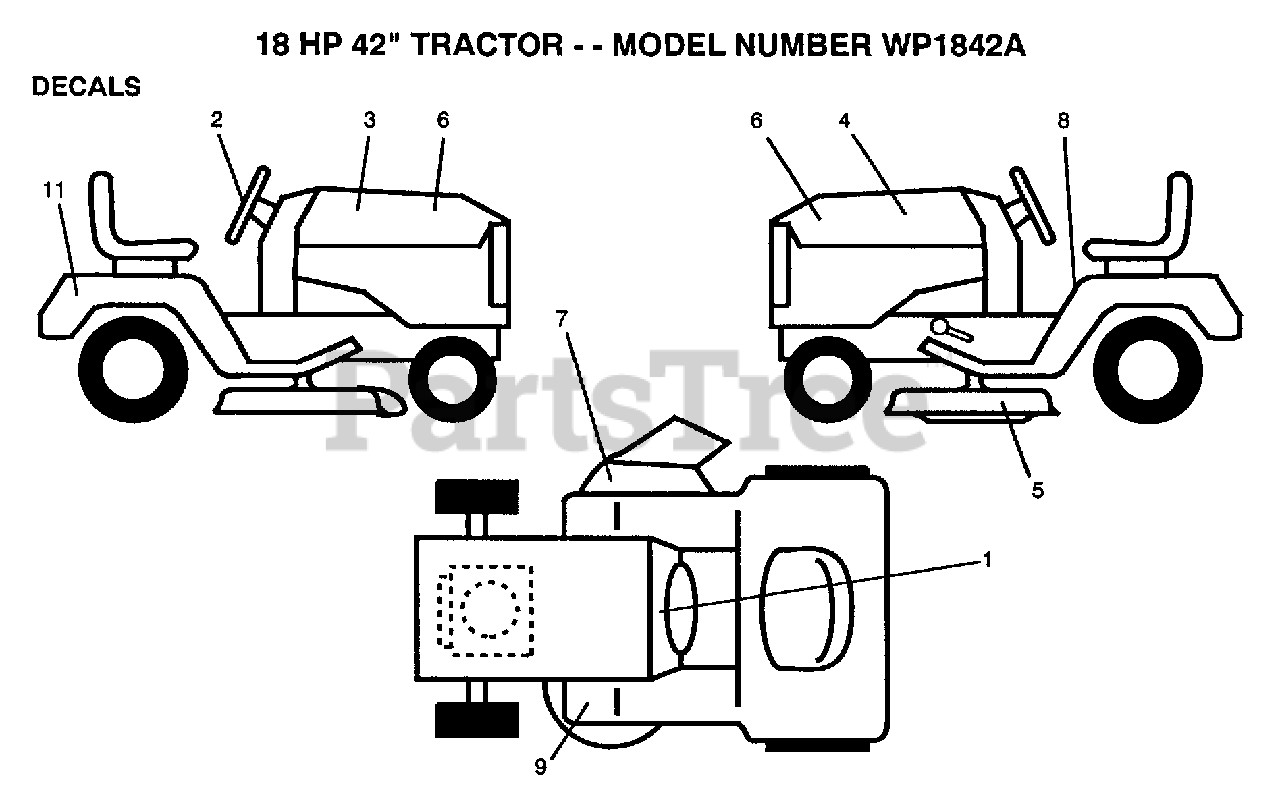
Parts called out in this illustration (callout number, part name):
2	DECAL, INSERT
3	DECAL.HOOD.RH
4	DECAL.HOOD.LH
5	DECAL INSTRUCTION CAUTION
6	DECAL, MODEL HOOD
7	DECAL WARING
8	DECAL
11	DECAL, LOGO, FENDER
